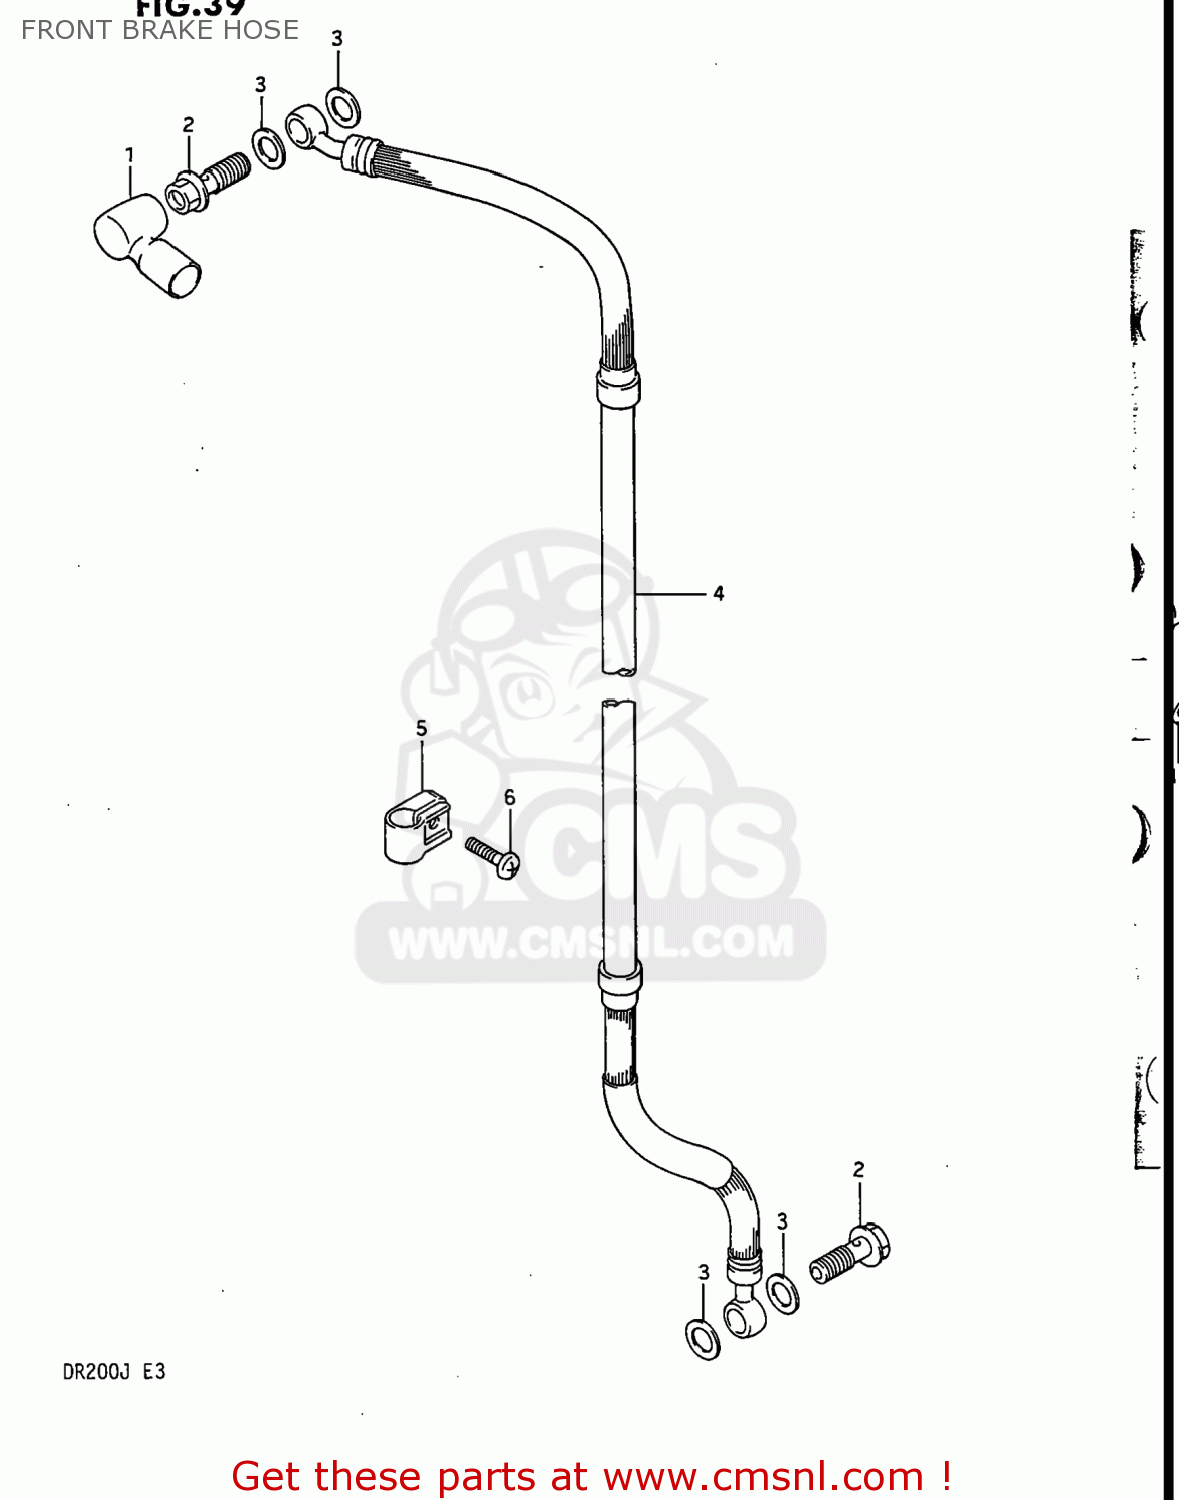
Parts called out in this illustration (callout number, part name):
1	BOOT,MASTER CYLINDER
2	BOLT UNION
3	WASHER(10X15X1.5)
4	HOSE,FRONT BRAKE
5	CLAMP,BRAKE HOSE
6	SCREW
